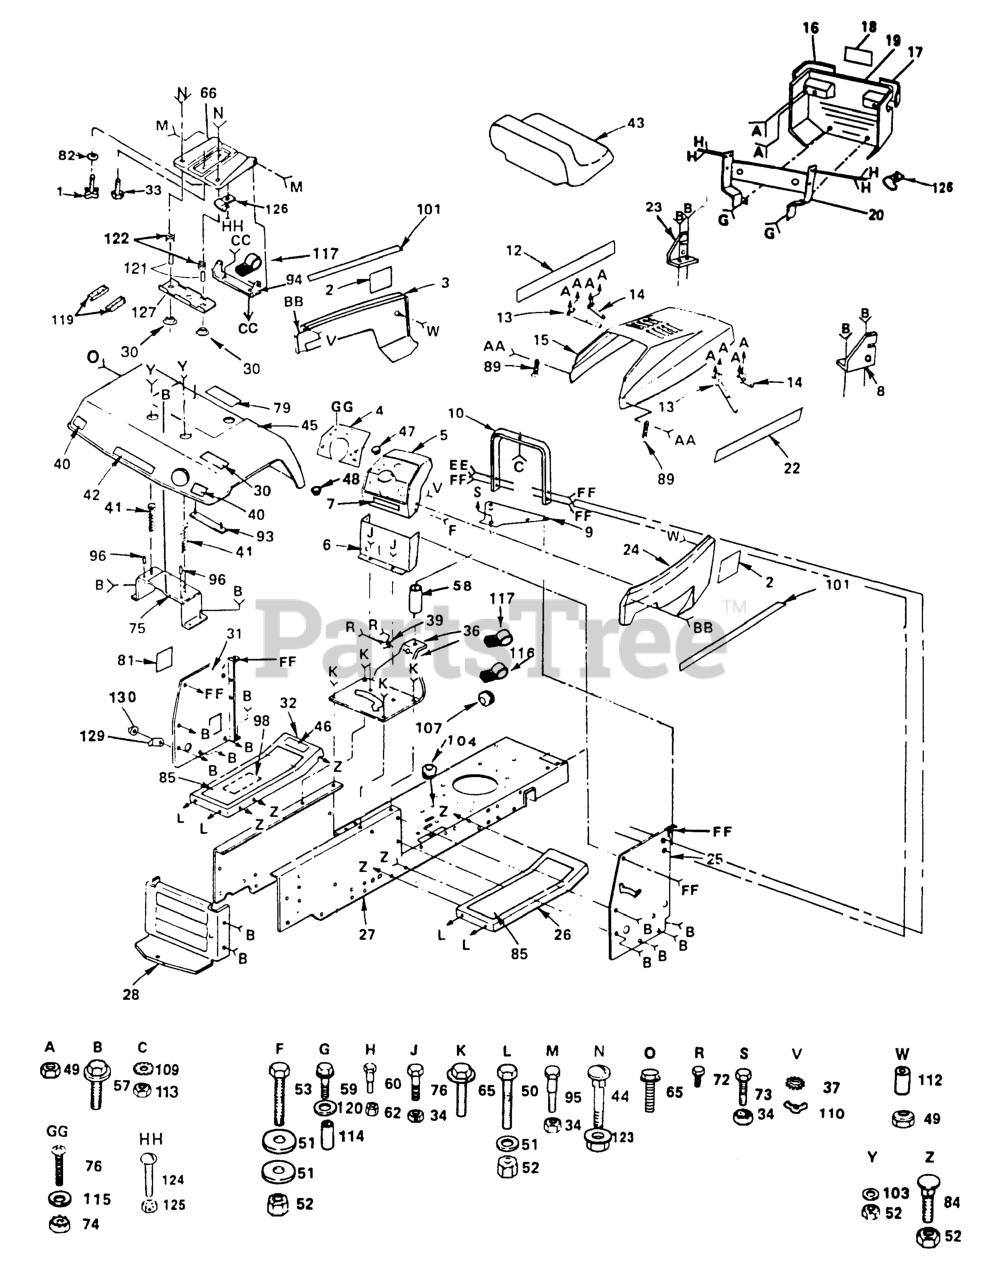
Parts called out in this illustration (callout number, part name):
1	KNOB 1/2" YT
2	DECAL,SIDE PANEL
3	PANEL,SIDE LH
4	DASH PLATE
5	DASHBOARD
6	DASH ASSY LT NLA
8	SUPPORT RH YTH
9	PLATE SUPPORT T NLA
10	SUPPORT ASS'Y
12	DECAL,HOOD LH NLA
13	STRAP ASSY LT
14	STRAP ASSY LT
15	HOOD
16	LENS LH
17	LENS RH
18	DECAL,GRILL HUSKY
19	GRILL
20	SUPT, ASS'Y GRILL
22	DECAL,HOOD RH
23	SUPPORT LH YTH
24	PANEL,SIDE RH
25	PANEL LT NLA
26	FOOTREST RH
27	CHASSIS ASSY NLA
28	DRAWBAR
31	PANEL DASH LH NLA
32	FOOTREST LH
33	BOLT, SHOULDER**
34	LOCKNUT
37	LOCKWASHER GT
39	BUSHING LT
40	REFLECTOR-TAIL YT
41	SPRING COMPRESSION
42	DECAL,FENDER HUSQ
43	SEAT
44	Bolt, Carriage 1/4 - 20 x 11/4
47	PLUG BUTTON T
48	PLUG-DASH T
49	NUT
51	WASHER
53	BOLT
57	SCREW
60	BOLT T
62	NUT.CROWNLOCK.1/4
65	SCREW LT
69	SCREW LT
72	SCREW LT
73	Bolt, Hex 5/16-18 x 2 Gr 2
74	NUT
75	BRACKET-FENDER YT
76	Screw, Mach. 5/16-18 x 3/4
81	COVER ACCESS
84	BOLT
85	PAD FOOTREST T
89	LATCH.HOOD.
93	STRAP-FENDER YT
94	BRKT,SEAT PIVOT**
95	BOLT, SHOULDER LT
96	NUT-PUSH YT
101	DECAL,SIDE PANEL
103	WASHER
104	SNAP BUSHING T
107	SNAP BUSHING T
109	Lockwasher, 1/4 Int. Ext.
110	NUT.WING.LCK.NYL.NOTCH.1/4-20
112	SPACER NLA
113	NUT
115	WASHER
116	INSUL CLIP T
117	CLIP T
119	STRIP FORM
120	WASHER PM
121	SPACER SPLIT
123	NUT T
125	Nut, Keps, #10-32 UNF
126	CLIP T
127	BRKT SWITCH
128	HEIGHT INDICATOR
129	POINTER HGT INDAT
132	DECAL,GRILL NLA
133	WASHER
